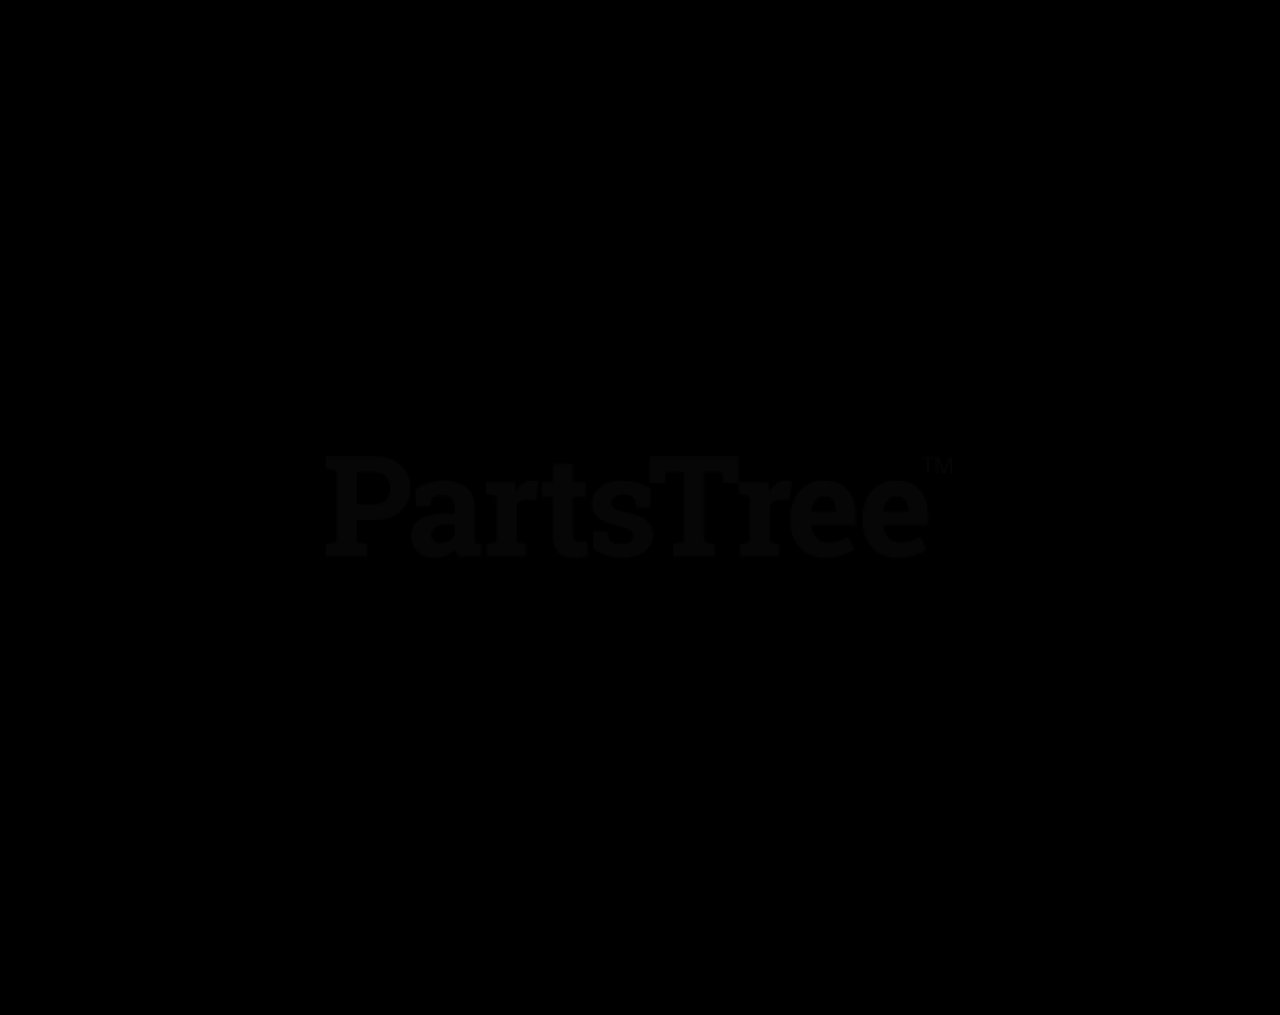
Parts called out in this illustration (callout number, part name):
1	Chute, Rubber Discharge
2	Nut, Locking, Nylon, Flange .38-16
3	Washer, Flat Steel .438 x 1.00 x .083
4	Support, Rubber Discharge Chute
5	Bolt, Hex .38-16 x 1.25
6	Bolt, Round Head Square Neck .38-16 x 1.00
7	Plate, Discharge Chute Support
8	Guard, Belt, Right – 60" Deck
9	Rivet, Pop, 0.187
10	Bolt, Hex 0.38-16 x 1.25
11	Washer, Locking, Ext. 0.391 x 0.628 x 0.036
12	Keeper, Bolt
13	Bolt, Round Head Square Neck .50-13 x 5.00
14	Guard, Belt, Left Hand Spindle
15	Weldment, 60" Rear Discharge Deck
16	Anti-Scalp Wheel
17	Spacer, .510 x .625 x 3.35
18	Nut, Locking, Nylon Flange .50-13
19	Bolt, Round Head Square Neck .50-13 x 8.50
20	Spacer, .510 x .625 x 6.70
